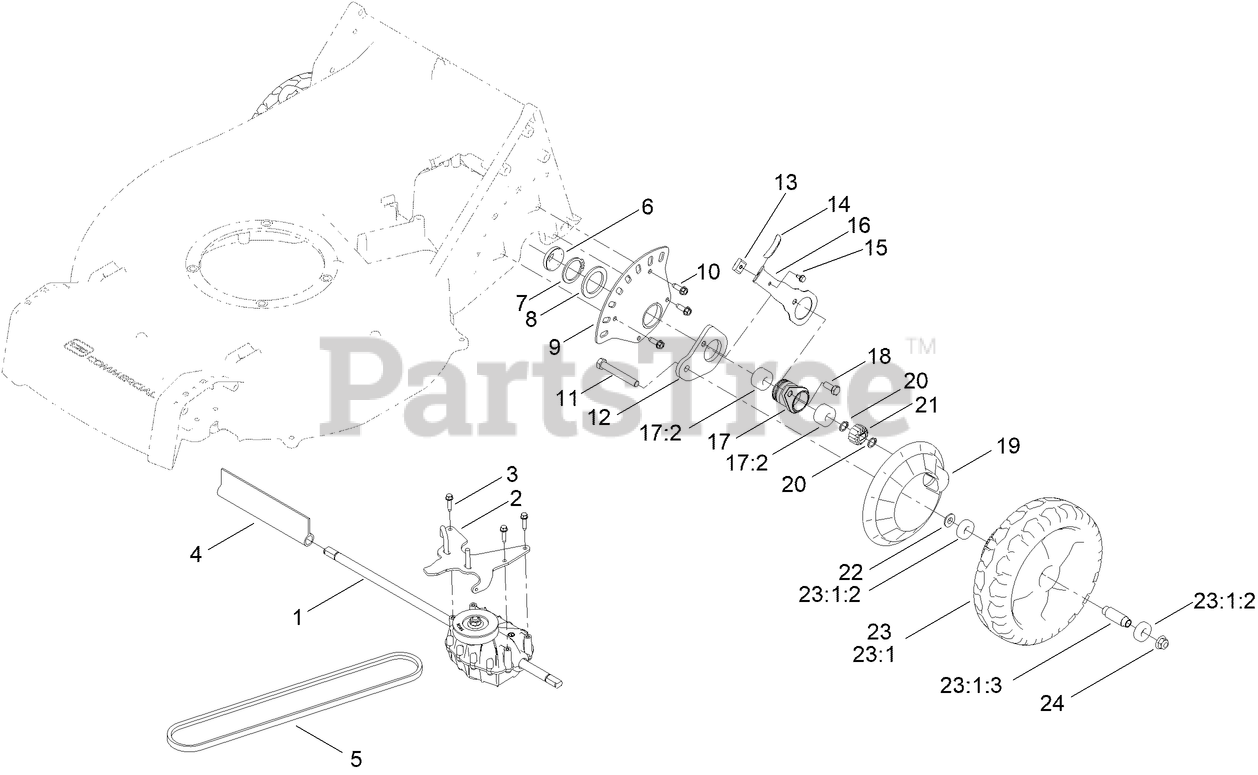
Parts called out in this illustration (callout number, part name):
1	TRANSMISSION-HD
2	BELT GUIDE ASM
3	SCREW-SPECIAL
4	COVER-SHAFT, TRANSMISSION
5	BELT-V
6	COVER-BEARING
7	RING-RETAINING
8	WASHER-THRUST
9	PLATE-HOC, REAR
10	SCREW-HWHTF
11	SCREW-HH
12	ARM-PIVOT, REAR
13	KEY-ARM, SPRING
14	KNOB-LEVER, HOC
15	SCREW-HWH
16	ARM-SPRING, REAR
17	BEARING RETAINER ASM
17:2	BEARING-BALL, CUSTOM
18	SCREW-HH
19	COVER-WHEEL
20	RING-RETAINING
21	GEAR-PINION, 15T
22	SPACER-COVER, WHEEL
23	9-INCH WHEEL ASM
23:1	WHEEL
23:1:2	BEARING-BALL
23:1:3	SPACER
24	NUT-HF, NI
